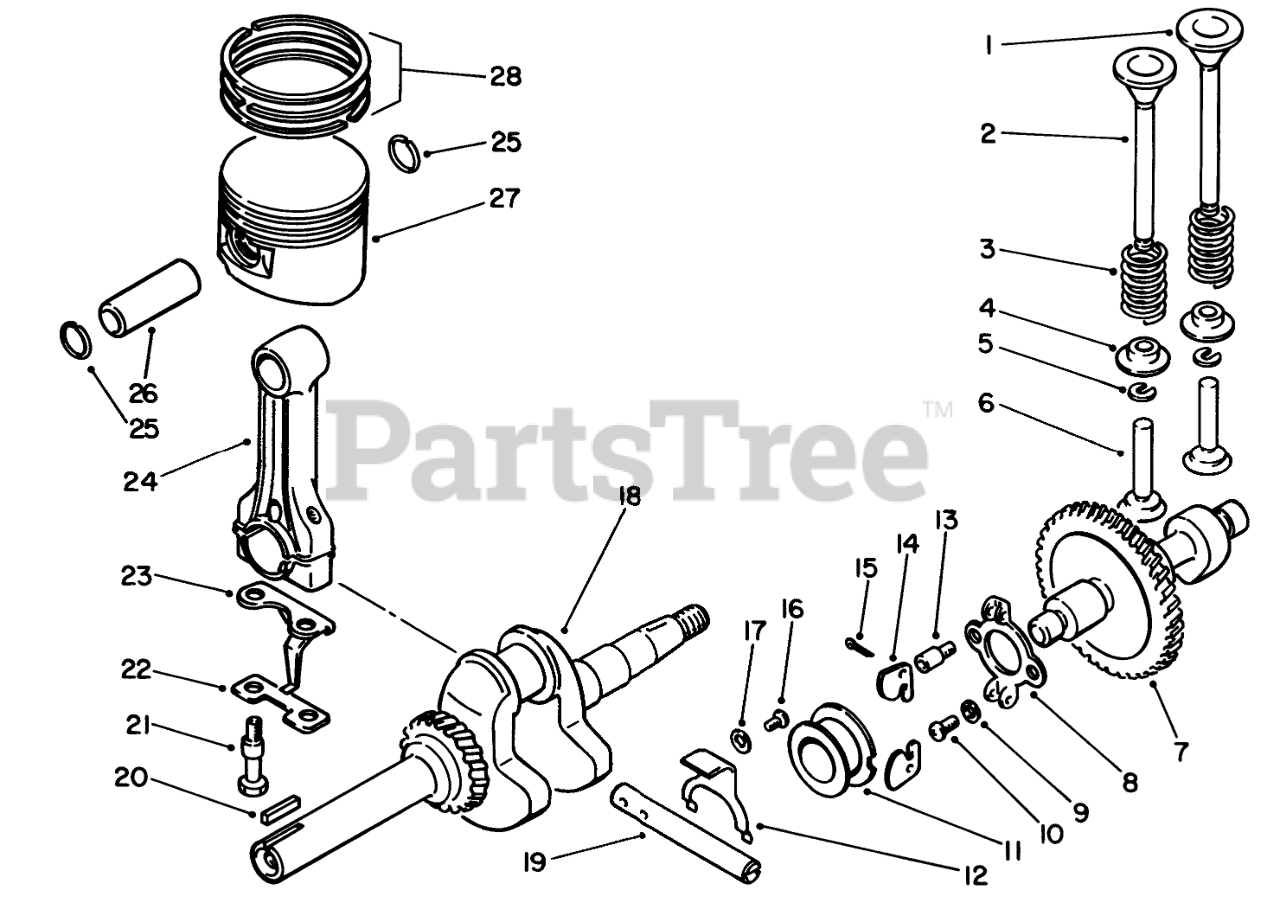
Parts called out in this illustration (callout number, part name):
1	VALVE, INTAKE
2	VALVE, EXHAUST
3	Spring-Valve
4	Retainer-Spring
5	Cotter-Valve
6	TAPPET
7	Cam Shaft
8	BRACKET
9	Washer
11	Spacer
12	SHIFT PLATE
13	SPACER-HOC ADJUSTMENT
15	Cotter Pin
16	SCREW
17	Washer
18	Crankshaft Assembly
19	SHAFT-THROTTLE TURN
22	LOCK PLATE
23	Plate-Splasher
24	Connecting Rod Assembly (Incl. Ref. #21-23)
25	CIRCLIP
26	Pin Piston
27	Piston Std.
28	Ring Set-Piston Std.
